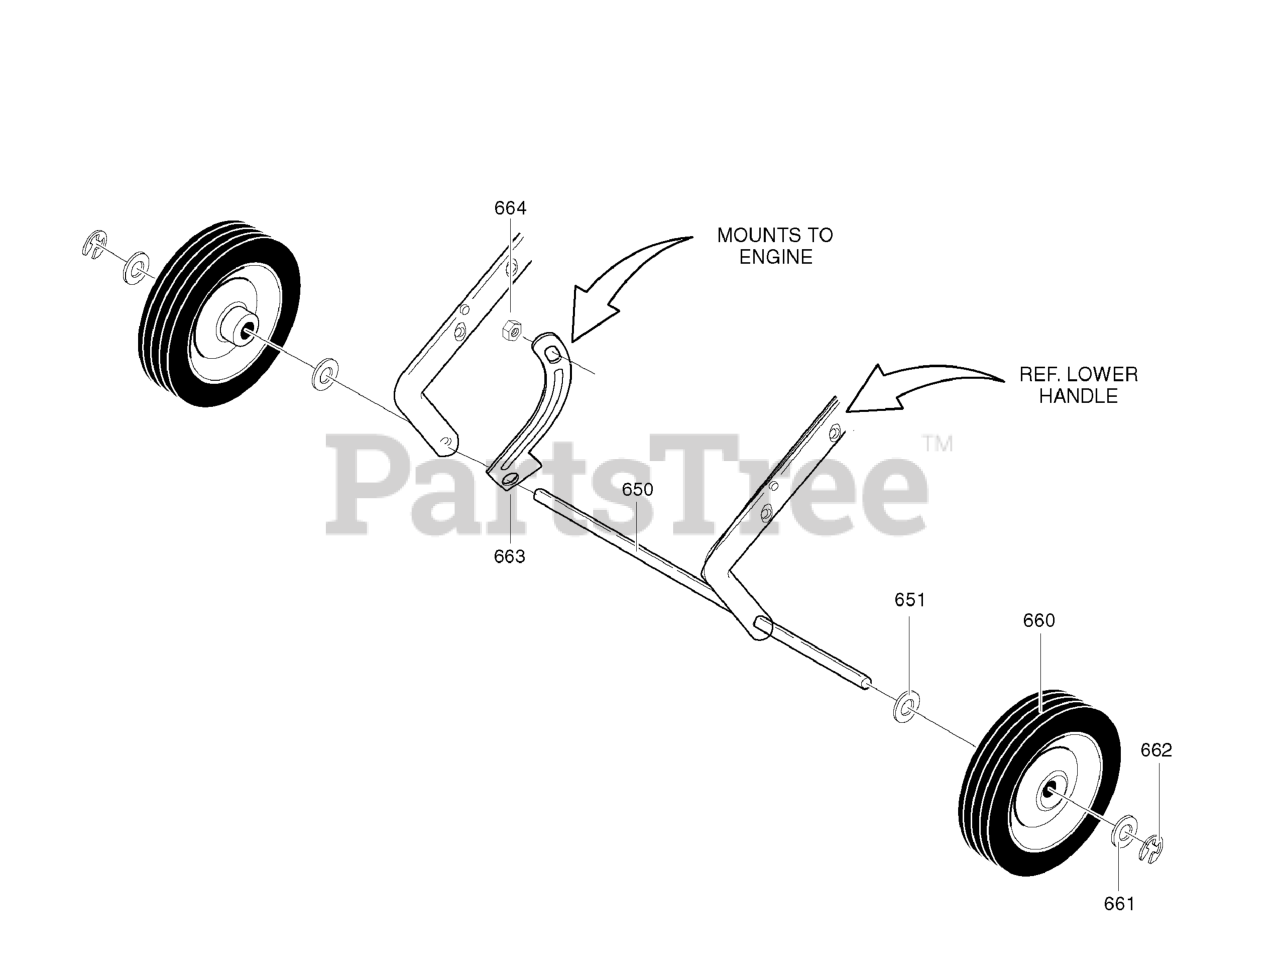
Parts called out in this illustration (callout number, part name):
650	AXLE SHAFT
651	WASHER, FLAT .391 X 1.00 X 1.25
660	TIRE & RIM
661	WASHER, FLAT .391 X 1.00 X .125
662	RING, RETAINER E
663	BRACKET, AXLE
